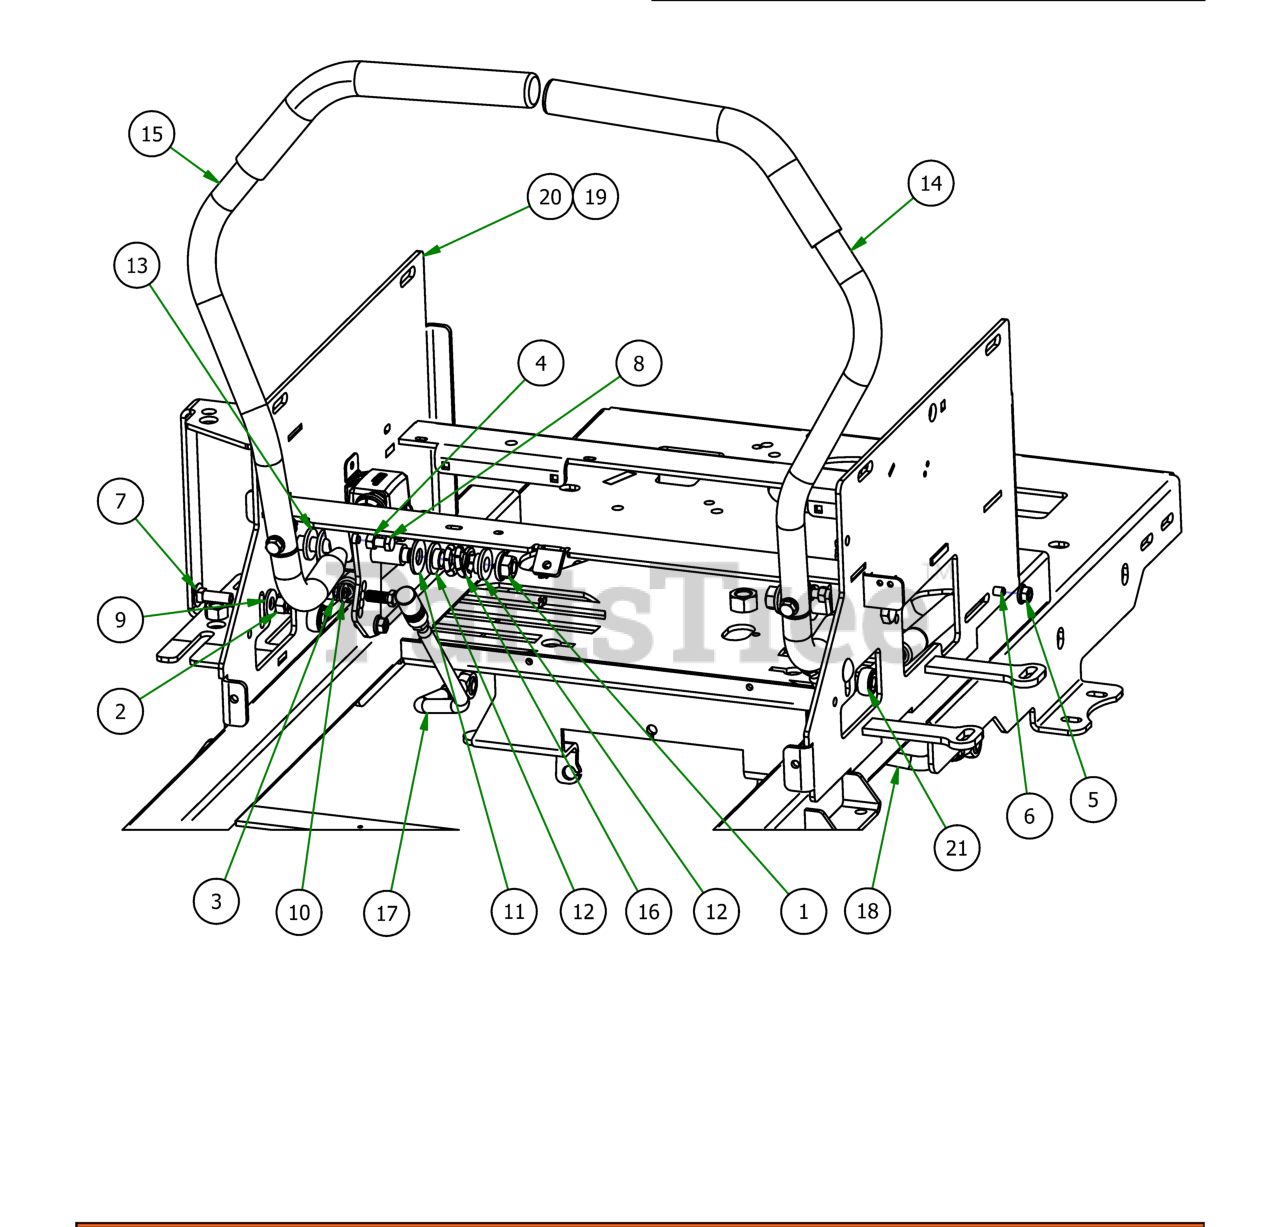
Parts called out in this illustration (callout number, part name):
1	1/2-13 Mechanical Lock Nut
2	3/8" Hex Nut
3	3/8" Fine Threaded Jam Nut
5	5/16" Flange Nut
6	10mm Damper Ball Stud-Steering
7	3/8" x 1 1/4" Carriage Bolt
8	5/16" x 3/4" Hex Bolt
9	3/8" Flat Washer
10	3/8" Lock Washer
11	1/2" Washer (Grade 8)
12	.515 ID Nylon Shoulder Washer
13	.505 Nylon Spacer
14	ZT Steering Arm Assembly, Left Hand
15	ZT Steering Arm Assembly-Right Hand
16	Drive Lever Spring
17	Push Rod-Right
18	Push Rod-Left
19	2017 MZ/ZT 54"-60" Frame
20	2017 MZ/ZT 42"-48" Frame
21	Steering Damper
